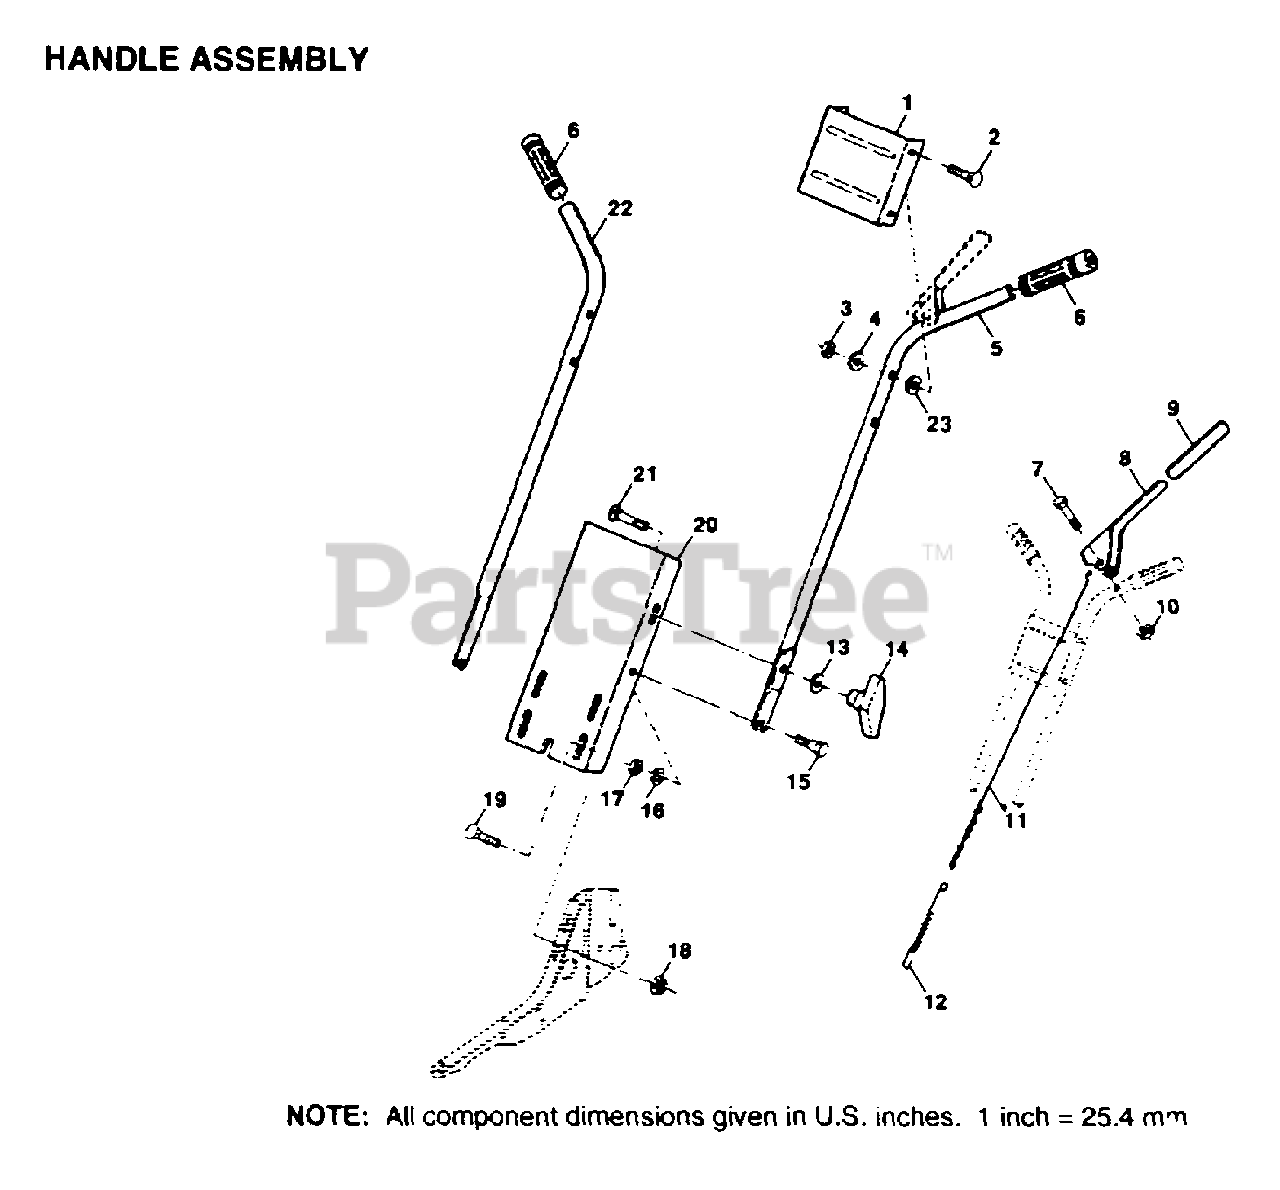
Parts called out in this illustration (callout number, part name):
1	BRKT. HANDLE
2	BOLT
4	WASHER
7	BOLT.HEX.5/16-1.5
9	GRIP T
12	SPRING EXT TI
13	WASHER
14	KNOB HANDLE
16	LOCKWASHER
17	NUT.HEX.5/16-18
18	NUT
19	BOLT
20	"PANEL, HANDLE"
21	BOLT
23	WASHER
